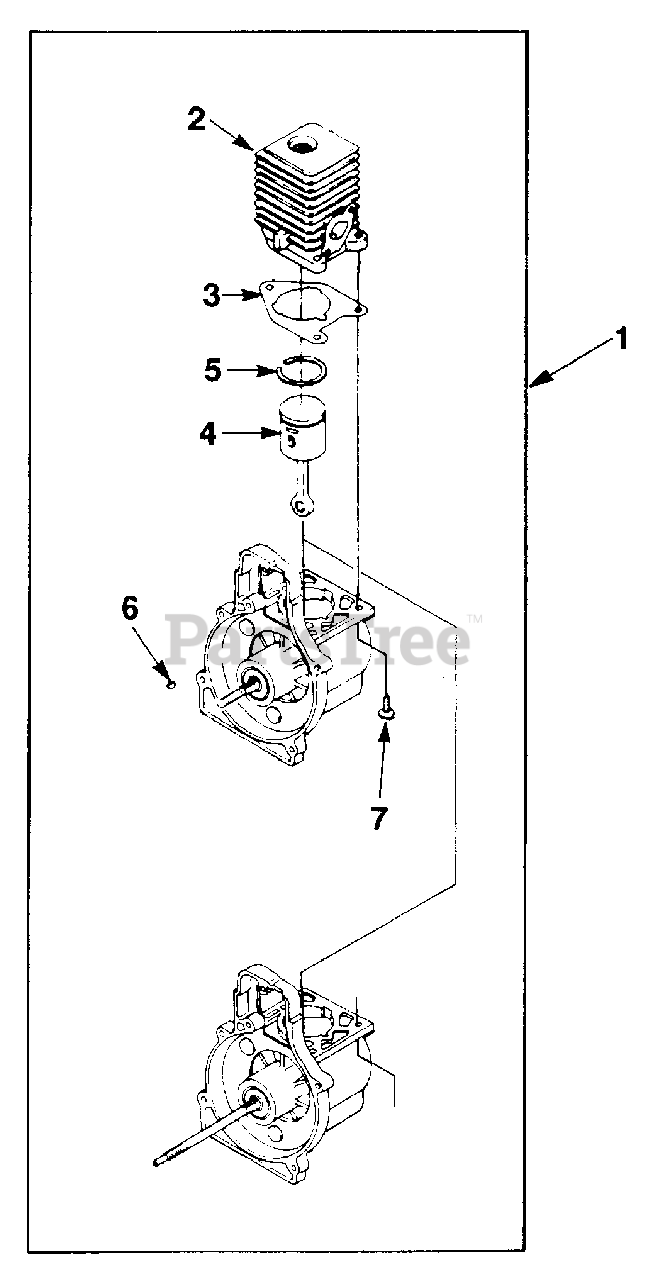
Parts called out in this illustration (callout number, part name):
1	SHORT BLOCK (25 CC Non-Clutch)
2	CYLINDER & GASKET (25 CC Non-Clutch)
3	GASKET-Cylinder (25 CC Non-Clutch)
4	PISTON & ROD (25 CC Non-Clutch)
5	RING-Piston (25 CC Non-Clutch)
6	KEY-Woodruff (25 CC Non-Clutch)
7	SCREW-Torx Pan Hd. (10-24 X 3/4") (25 CC Non-Clutch)
